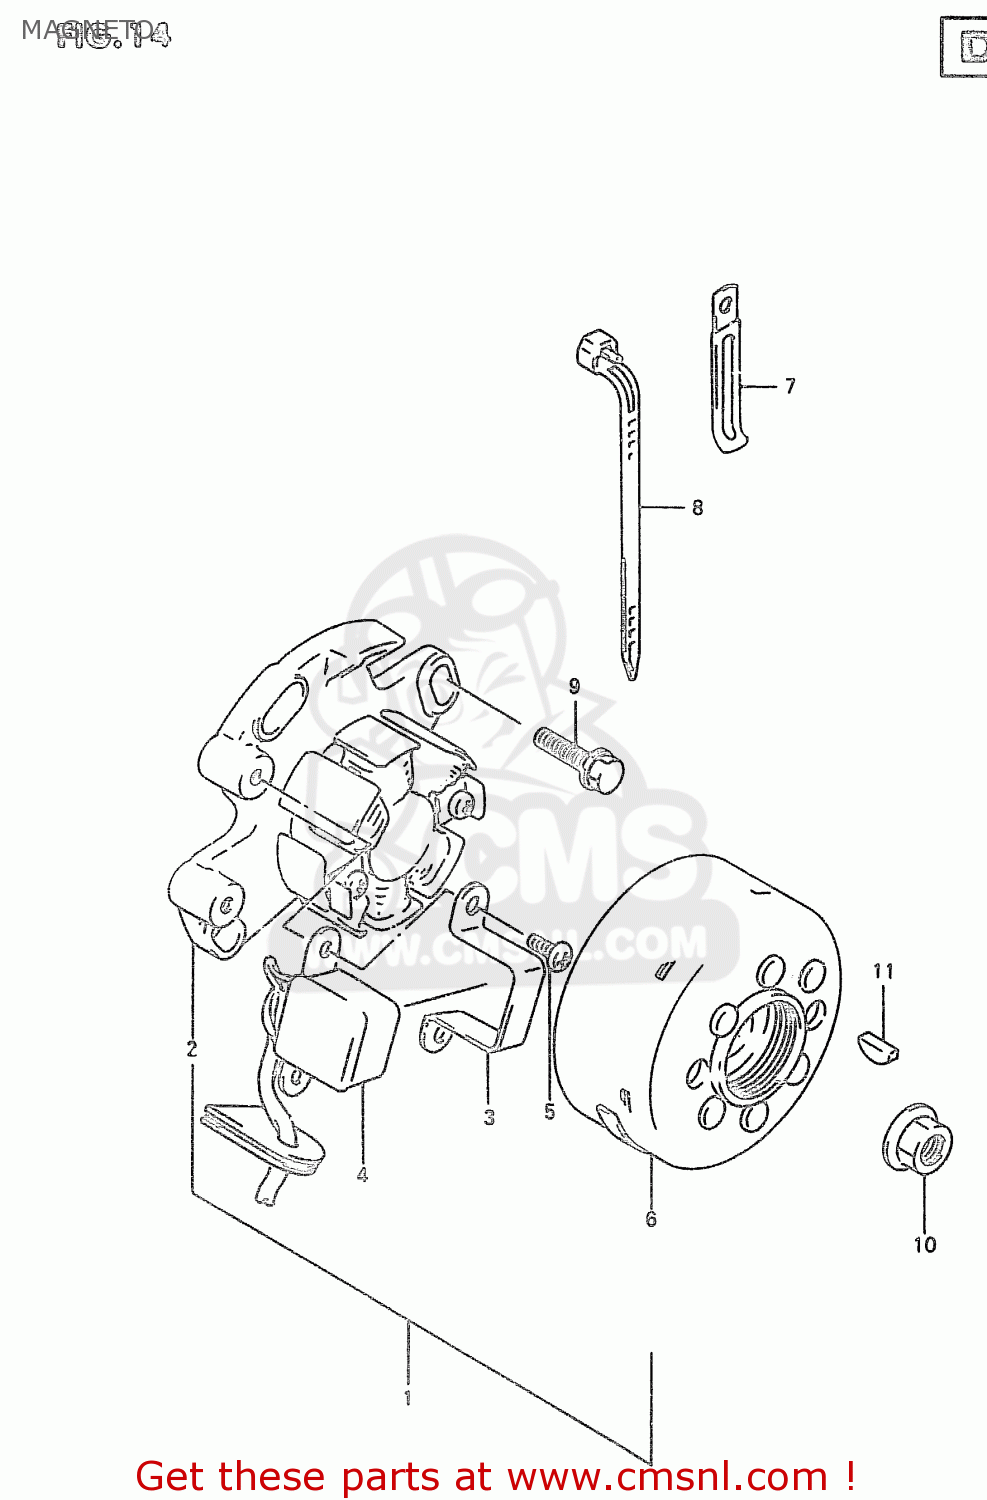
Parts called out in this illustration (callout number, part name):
1	MAGNETO ASSEMBLY
2	STATOR ASSEMBLY
3	HOLDER,PICK UP COIL
4	COIL,PULSER
5	SCREW
6	ROTOR
7	CLAMP(L:65)
8	CLAMP L:165
9	SCREW
10	NUT
11	KEY
